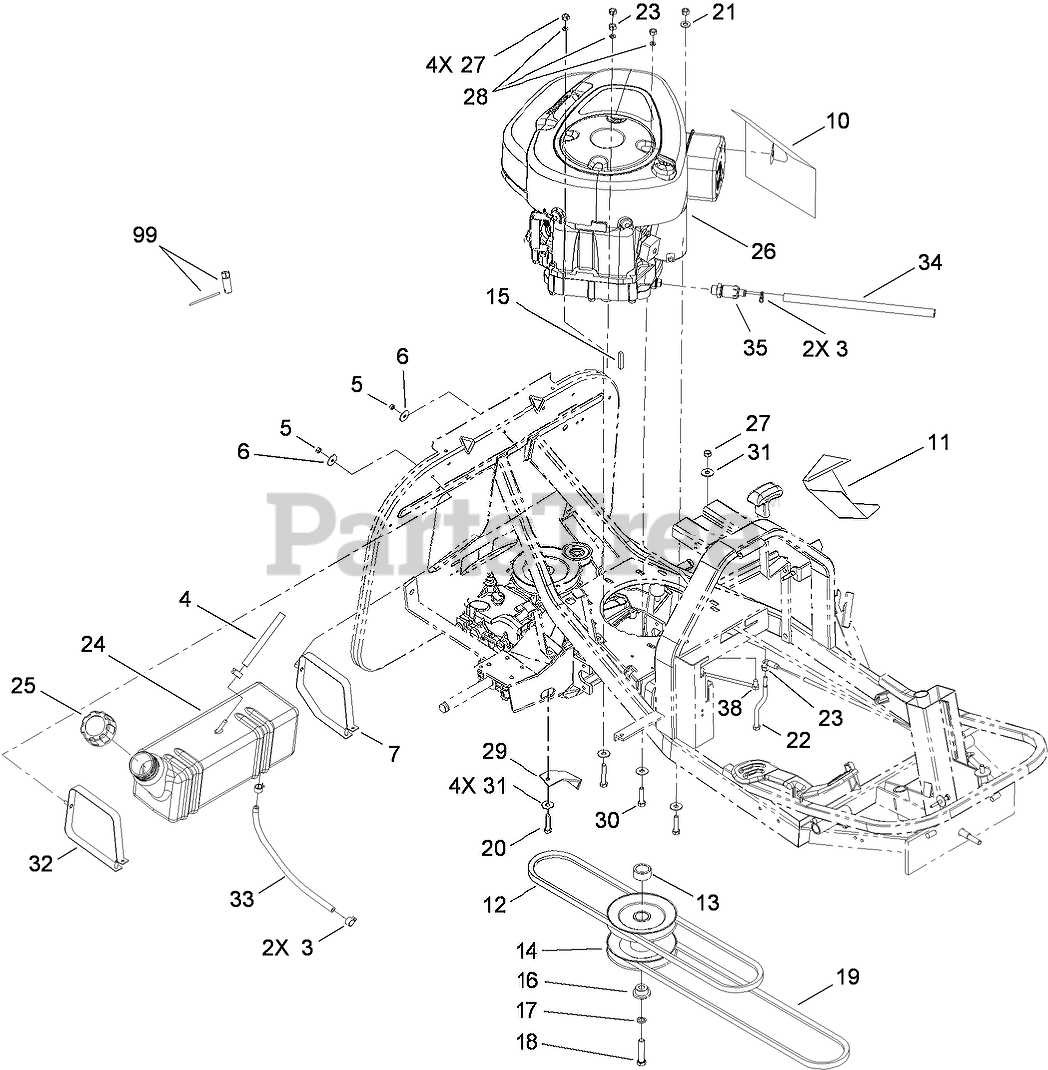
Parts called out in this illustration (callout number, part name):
3	CLAMP-TUBE
4	Hose-Fuel
5	NUT-LOCK
6	Washer-Flat
7	STRAP-FUEL TANK, LEFT
10	SHIELD-MUFFLER
11	DEFLECTOR-EXHAUST
13	Spacer
14	PULLEY
15	KEY-SQUARE
16	Spacer
17	Washer-Lock
18	SCREW-HH
19	BELT-DECK
20	SCREW-HH
21	WASHER-PLAIN
22	Guide-Belt
23	NUT-HEX
24	TANK-FUEL
25	GAS CAP ASM
27	NUT-LOCK
28	WASHER-FLAT
29	BRACKET, DRIVE BELT
30	Screw-HH
31	Washer-Flat
32	STRAP-FUEL TANK, RIGHT
33	Hose-Fuel
34	TUBE-DRAIN, OIL
35	VALVE-DRAIN, OIL
38	GUIDE-BELT
99	PLUG-WRENCH
